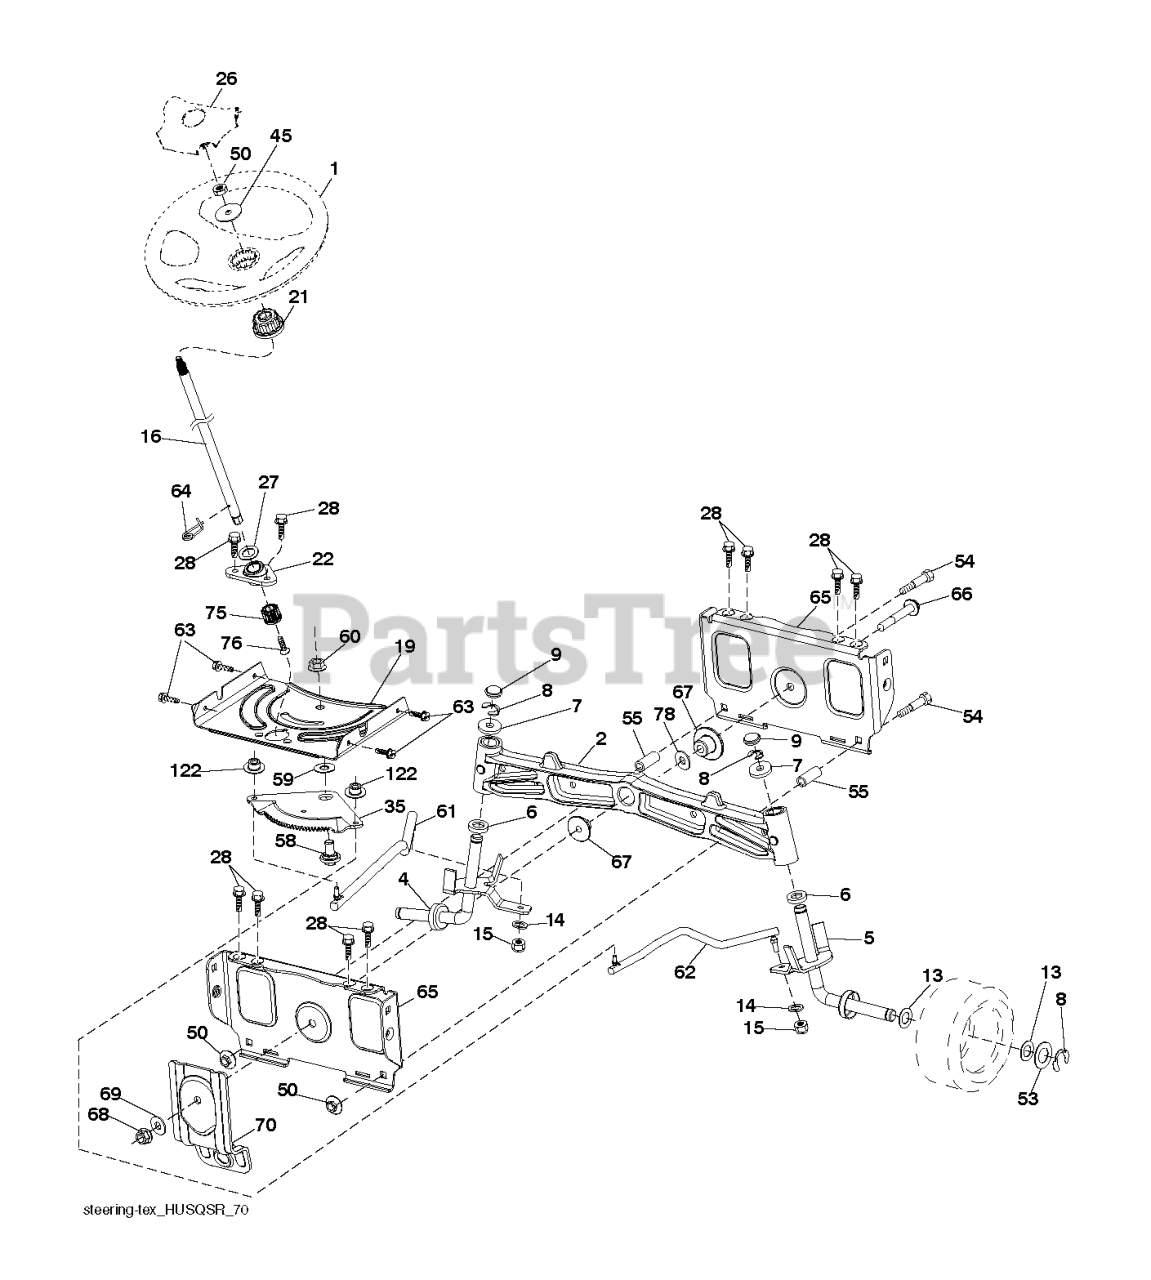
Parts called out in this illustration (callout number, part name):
1	WHEEL.STEER.HUSQ.SR.498.OVMLD
2	AXLE.CAST.IRON
4	SPINDLE.WELDED.LH.16"TEX
5	SPINDLE.WELDED.RH.16"TEX
6	THRUST WASHER
9	CAP.SPINDLE.BLACK
14	SLW 3/8 STD
15	NUT CROWNLOCK 3/8-24
16	SHAFT.STEER.2HIGH.SPLND.PLATED
19	PLATE.STEER.DDL.NLT/NG
21	ADAPTER.WHEEL.STEER.SPLND.ALUM
22	BEARING.SUBASM.SHAFT.STEER.LOW
26	INSERT.CAP.WHL.STRG.HUSQ.PREM
27	WASHER LT
28	SCREW, 3/8-16X3/4
35	GEAR.SECTOR.PLATE.DDL.
45	WASHER.3/8ID.2-3/8OD.12GA.PLTD
50	NUT LOCK FLG 3/8-16 UNC
53	WASHER.HARDENED
55	SPACER.BRACE.AXLE
58	BOLT.SHOULDER.SECTOR.P
59	WASHER.THURST.SECTOR.S
60	NUT FLANGE LOCK 5/8-11
61	LINK.ASM.DRAG.ADJUST.LH.PLATED
62	LINK.ASM.DRAG.ADJUST.RH.PLATED
63	SCREW
64	RETAINER.CLIP.SPRING.S
65	BRACE.AXLE.FRONT.NLT/N
66	BOLT HEX FGHD 7/16-14 X 3 SERR
67	BUSHING.PM.FRONT AXLE
68	NUT.LOCK.FLANGE.7/16
69	WASHER.1.5X.505X.118
70	BRACKET.FRT.DECK.SUSP.RR.MT431
75	PINION.ZINC PLATED
76	SCREW HEAD SOCKET LRVB
78	THRUST WASHER
122	CAP.GEAR.SECTOR.TEX
